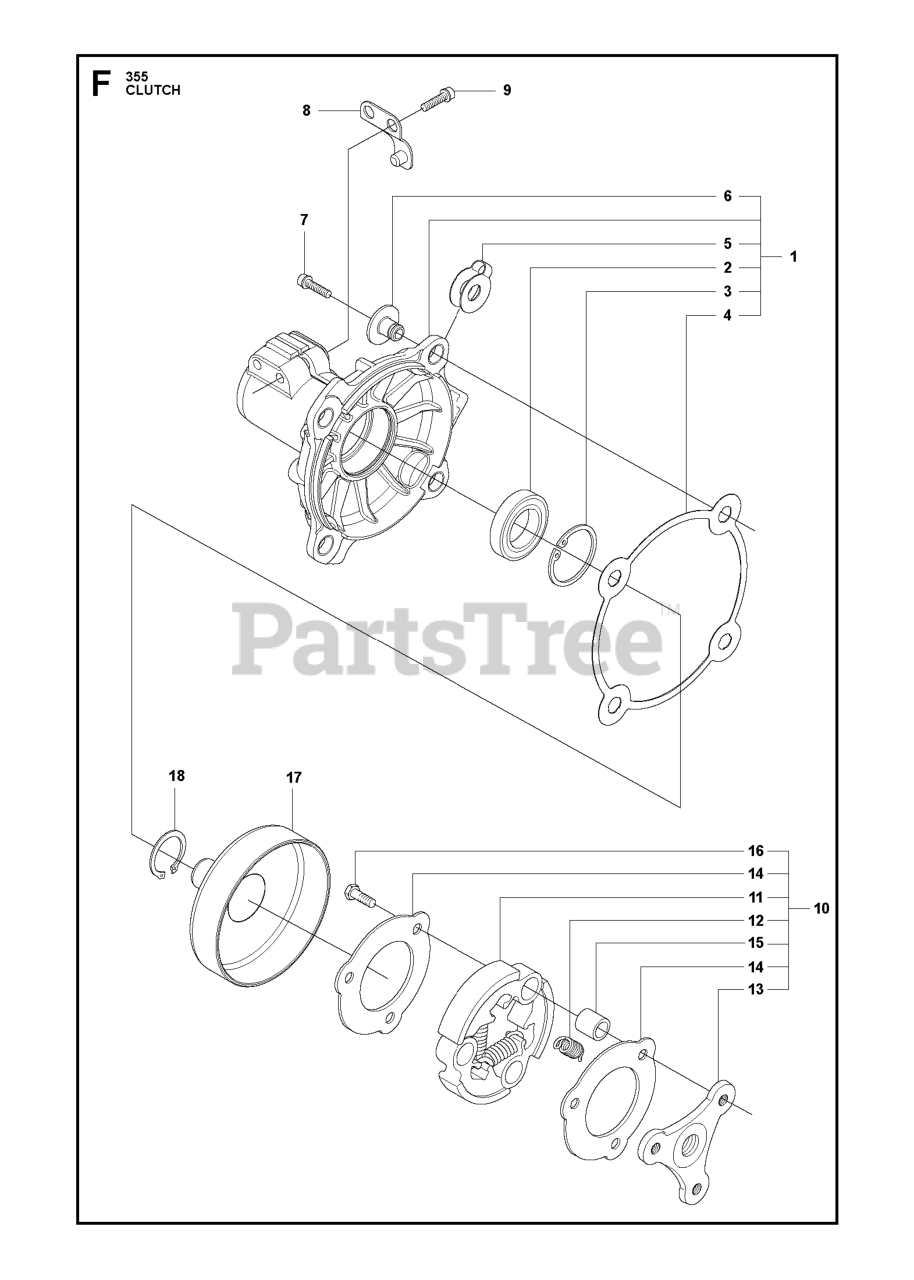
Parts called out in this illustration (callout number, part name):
1	CLUTCH COVER ASSY
2	BALL BEARING 6202-2RS1
3	RETAINING RING SGH 35
5	SPRING PLATE
6	SPACING SLEEVE
8	LOCKING PLATE
10	CLUTCH ASSY
11	CLUTCH SHOE
12	CLUTCH SPRING
13	CLUTCH HUB
17	CLUTCH DRUM ASSY
18	RETAINING RING SGA 15
